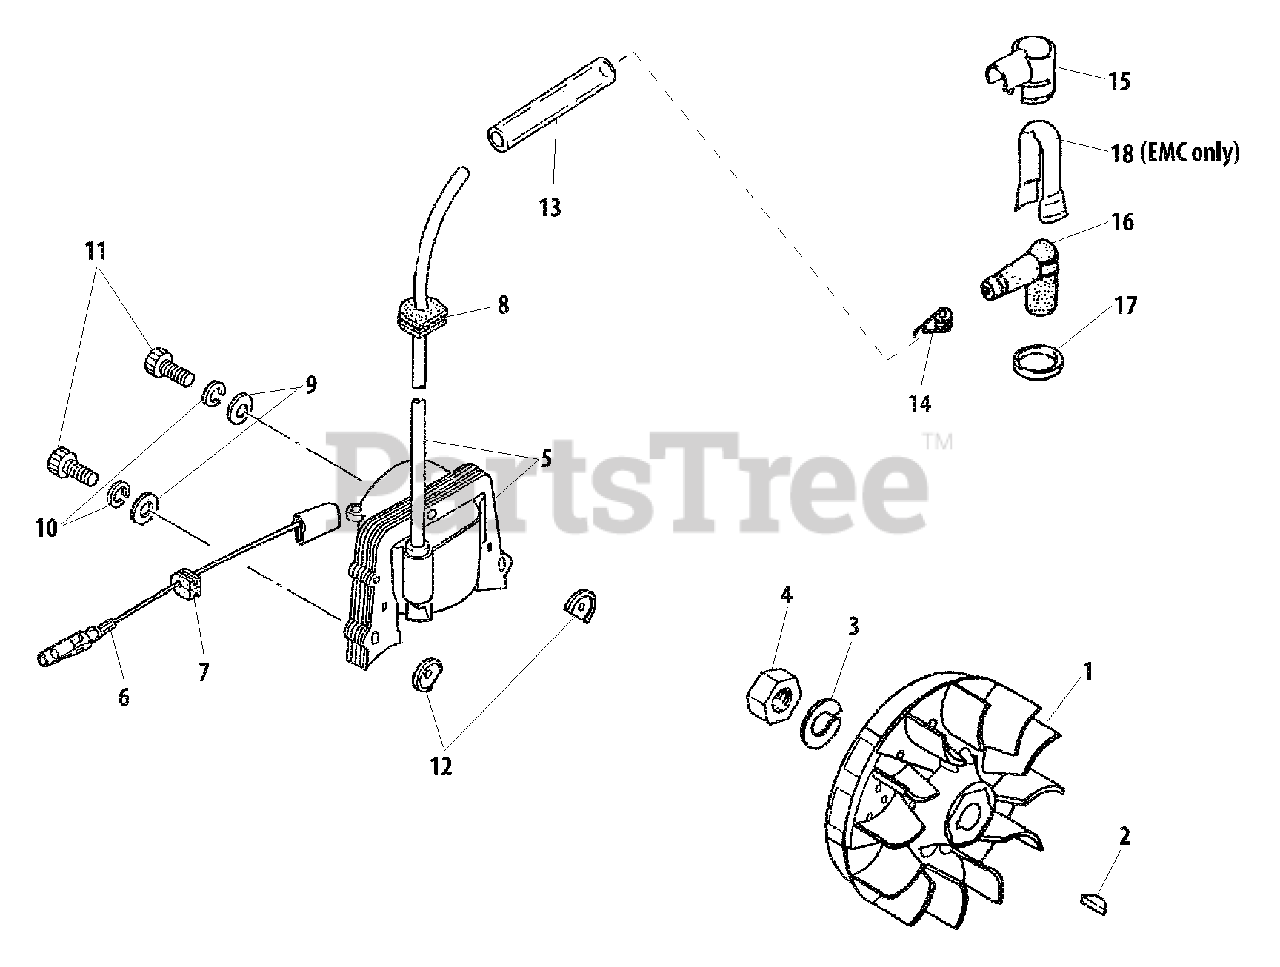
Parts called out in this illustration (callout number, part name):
1	FLYWHEEL
2	KEY - 3X10
3	LOCKWASHER - 10
4	NUT - 10
5	COIL, IGNITION
6	WIRE
7	GROMMET
8	GROMMET
9	WASHER
10	LOCKWASHER - 4
11	SCREW - 4X24
12	INSULATOR
13	TUBE
14	TERMINAL, SPARK PLUG CAP
15	CAP, SPARK PLUG
16	CAP, SPARK PLUG
17	SEAL, DUST
18	SHIELD
